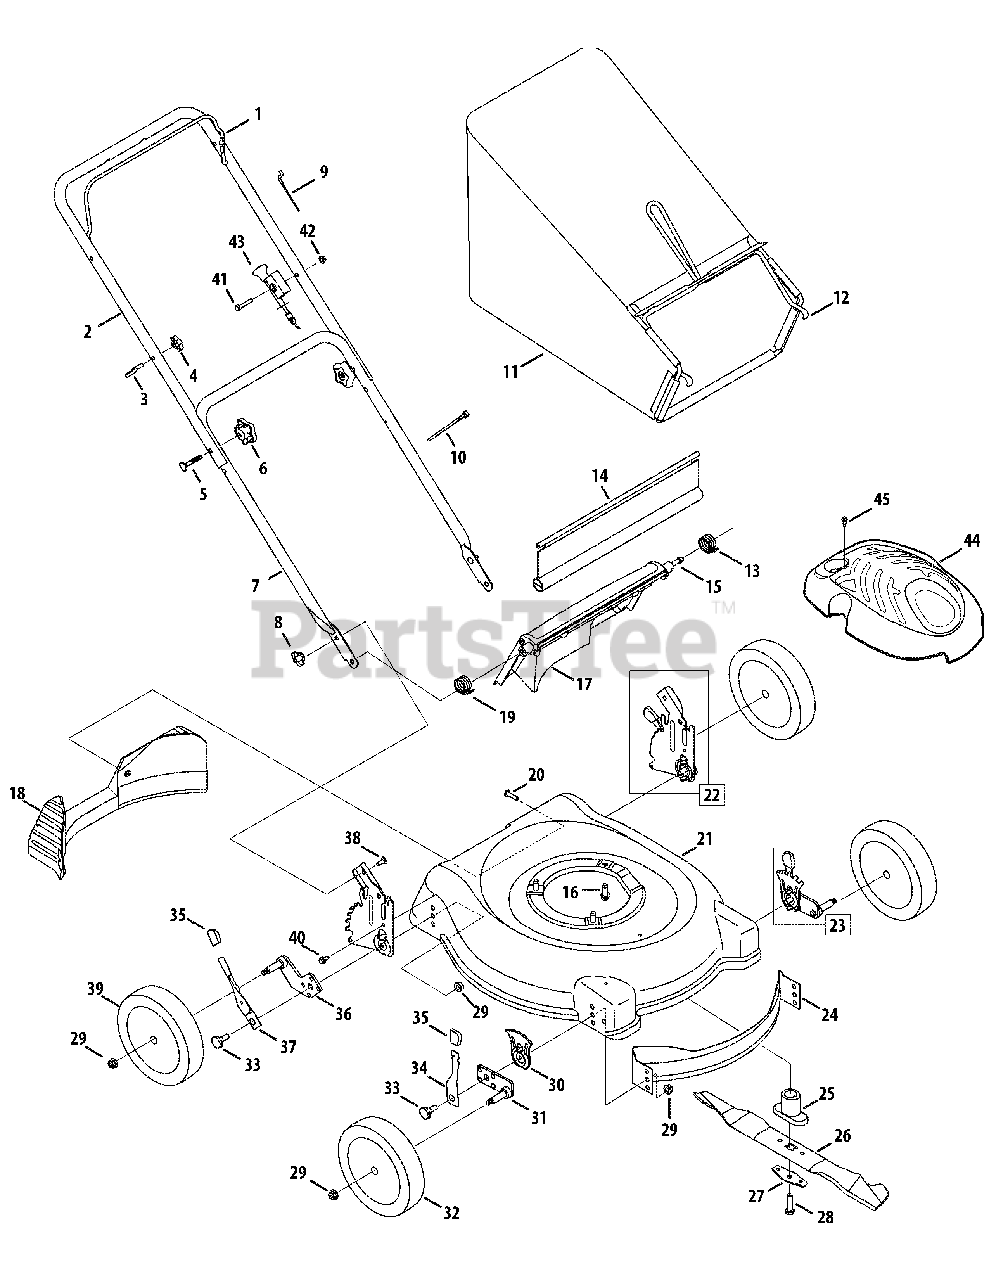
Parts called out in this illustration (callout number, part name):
3	Rope Guide
4	Wing Nut, 1/4-20
5	Carriage Bolt, 5/16-18 x 2
6	Hand Star Knob
8	Wing Nut, 1/4-20
9	Control Cable
10	Cable Tie
11	Grass Bag
13	Torsion Spring
14	Trailshield
15	Rear Door Pivot Rod
16	TT Screw, 3/8-16 x 1
17	Rear Discharge Door
18	Rear Baffle
19	Torsion Spring - RH
20	Screw, 1/4-15 x 1.00
22	Handle Bracket Assembly- RH
22	Handle Bracket Assembly - LH
23	Height Adjustment Assembly Front - LH
23	Height Adjustment Assembly Front - RH
24	Front Baffle
25	Blade Adapter, #6 x 2.15 w/Star
26	Mulch Blade
27	Blade Bell Support
28	Screw, 3/8-24 x 2.50
29	Flange Lock Nut, 3/8-16
30	Height Adjusment Plate
31	Front Pivot Arm Assembly - RH
31	Front Pivot Arm Assembly - LH
32	Front Wheel, 7 x 1.8
33	Shoulder Screw, .500 Dia x .385
34	Spring Lever
35	Height Adjustment Knob
36	Rear Pivot Arm Assembly - RH
36	Rear Pivot Arm Assembly - LH
37	Spring Lever
38	Carriage Bolt, 1/4-20
39	Rear Wheel, 8 x 1.8
40	Screw, 1/4-20 x .625
41	Screw, 1/4-20 x 1.50
42	Flange Lock Nut, 1/4-20
43	Choke Cable
44	Engine Shroud
45	Screw, Mach., M4-.7
